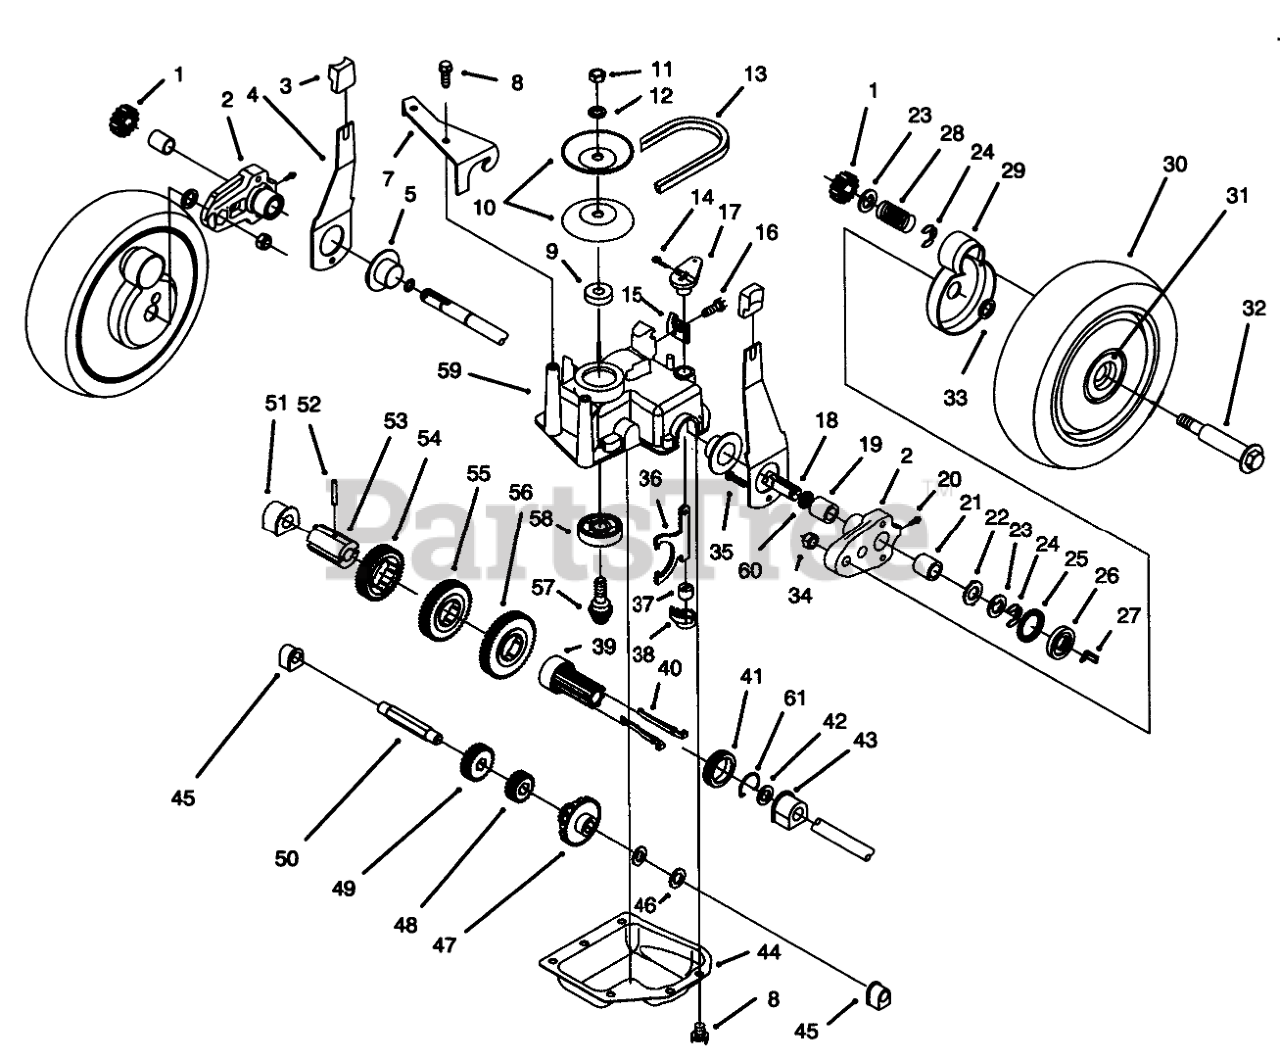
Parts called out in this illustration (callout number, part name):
1	GEAR-PINION
2	Pivot Arm Assembly (Incl. Ref #19, 20, & 21)
3	KNOB-ARM
4	SPRING ARM ASM
5	CAP-END
7	Bracket-Guide
8	SCREW-HWHTF
9	SPACER
10	Pulley Half
11	NUT-HEX
12	WASHER-FLAT
13	V-BELT E
14	PIN-COTTER
15	CLAMP-CABLE
16	SCREW-HWHTF
17	LEVER-SHIFT
18	SHAFT-OUTPUT
19	BUSHING
20	FITTING-GREASE
21	BEARING-ROLLER
22	WASHER-ARM, PIVOT
23	WASHER-THRUST, KEYED
24	RING-CLIP, LOCKING
25	RING-FRICTION
26	WASHER-CLUTCH
27	KEY-ROCKING, LH
28	SPRING-COMPRESSION
29	COVER-WHEEL
30	Wheel-Tire & Gear Asset (Incl. Ref. #31)
31	BUSHING
32	BOLT-WHEEL
33	SPACER-COVER, WHEEL
34	NUT-LOCK
35	SCREW-HWH
36	YOKE-SHIFT
37	BUSHING-YOKE
38	RETAINER-FORK, SHIFT
39	SLEEVE-KEY, SHIFT
40	KEY-SHIFT
41	COLLAR-SHIFT
42	WASHER-PLAIN
43	BUSHING-OUTPUT
44	Cover-Gearcase
45	BUSHING
46	WASHER-THRUST
47	Gear-Bevel
48	PINION-20T
49	PINION-25T
50	SHAFT-INTERMEDIATE
51	BUSHING
52	PIN-SPRING
53	SLEEVE-GEAR
54	GEAR-39T
55	GEAR-44T
56	GEAR-49T
57	Gear-Pinion
58	BEARING-BALL
59	CASE-GEAR, UPPER
60	O-RING
61	CLIP-SPRING
